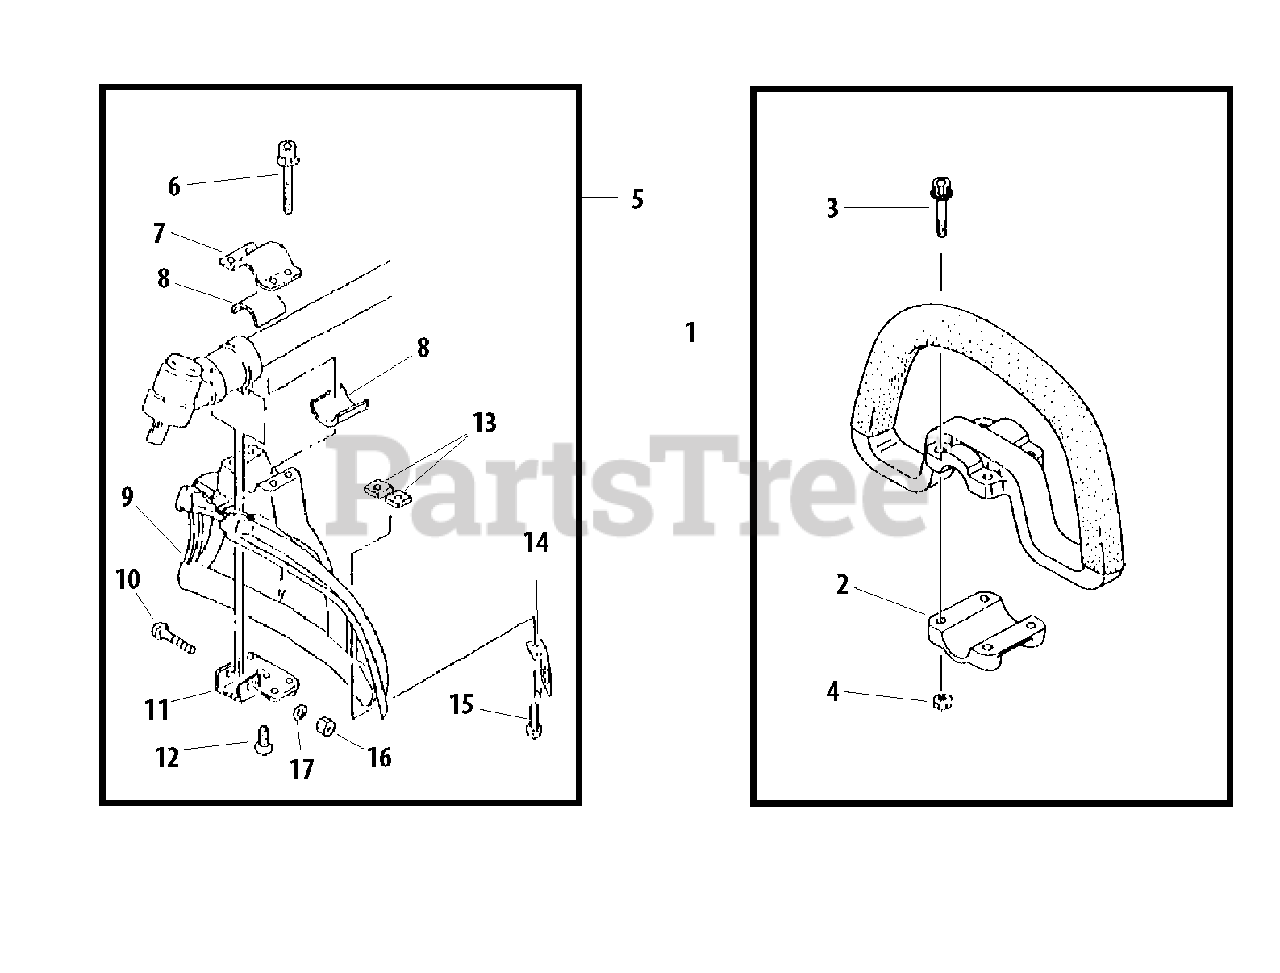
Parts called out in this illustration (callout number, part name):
1	HANDLE ASSY, FRONT
2	BRACKET, MOUNTING
4	NUT M5
5	DEBRIS SHIELD ASSY
6	BOLT M5×45
7	CLAMP, UPPER
8	SPACER
9	SHIELD, DEBRIS
10	BOLT M5×35
11	PLATE, SHIELD MOUNTING
12	SCREW HILO 4×10
13	NUT M5
14	CUTTER
15	BOLT M5×16
16	NUT M5
17	WASHER 5 MM
